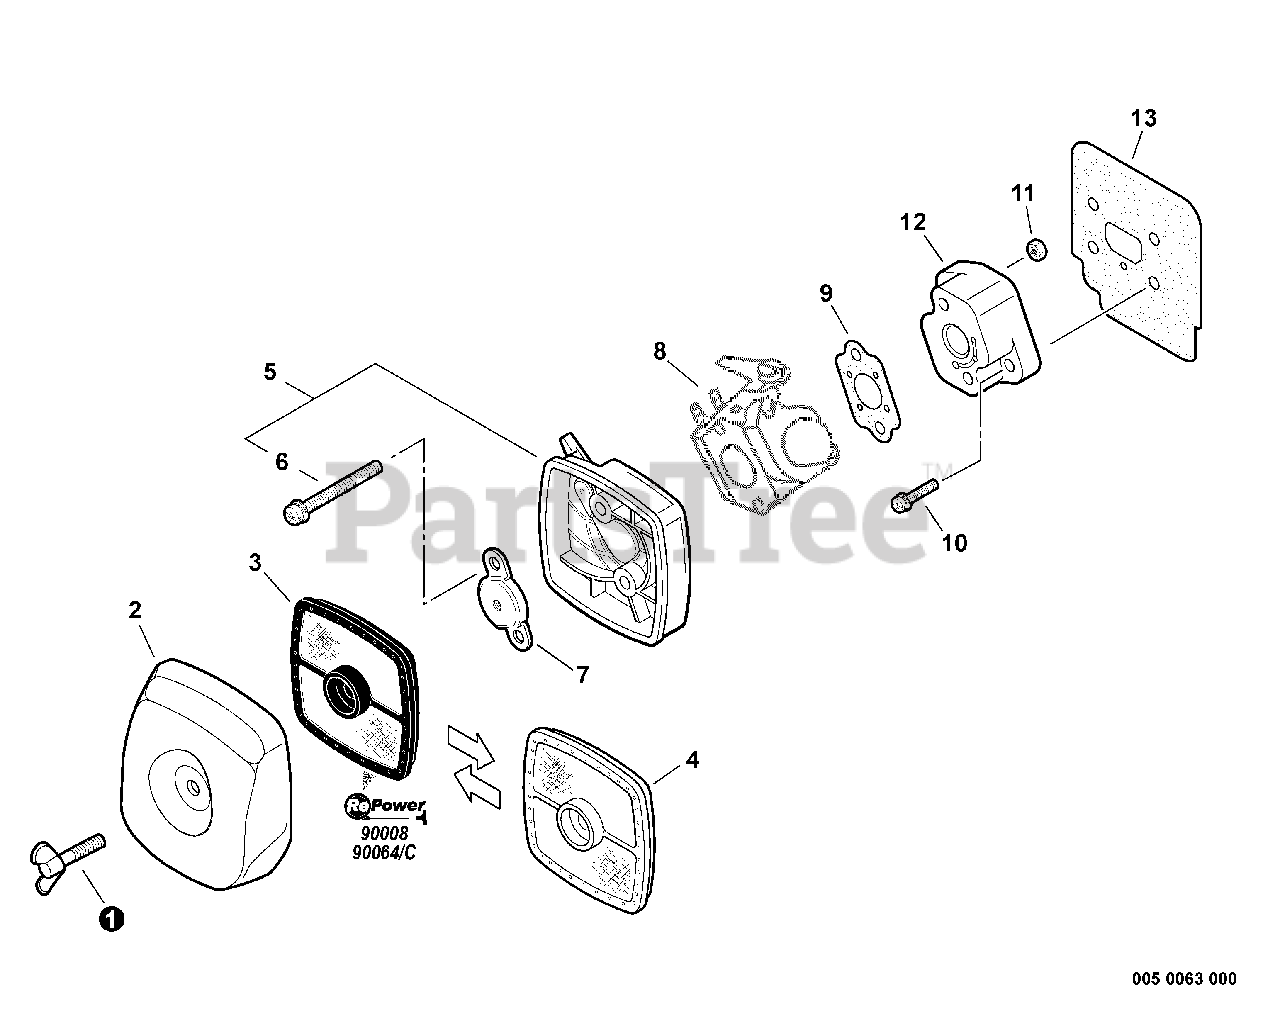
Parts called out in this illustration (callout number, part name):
1	BOLT, WING 5×20
2	COVER, AIR FILTER - GRAY
2	COVER, AIR FILTER - BLACK
3	FILTER, AIR - DOUBLE LAYER
4	FILTER, AIR - SINGLE LAYER
5	CASE, AIR FILTER - GRAY
5	CASE, AIR FILTER - BLACK
6	SCREW 5×65
7	PLATE, PREVENT
8	CARBURETOR
9	GASKET, INTAKE
9	TUNE-UP KIT
10	SCREW 5×20
11	INSULATOR, INTAKE
12	NUT M5
13	HEAT SHIELD, INTAKE
14	FILTER KIT - REPOWER
15	TUNE-UP KIT
